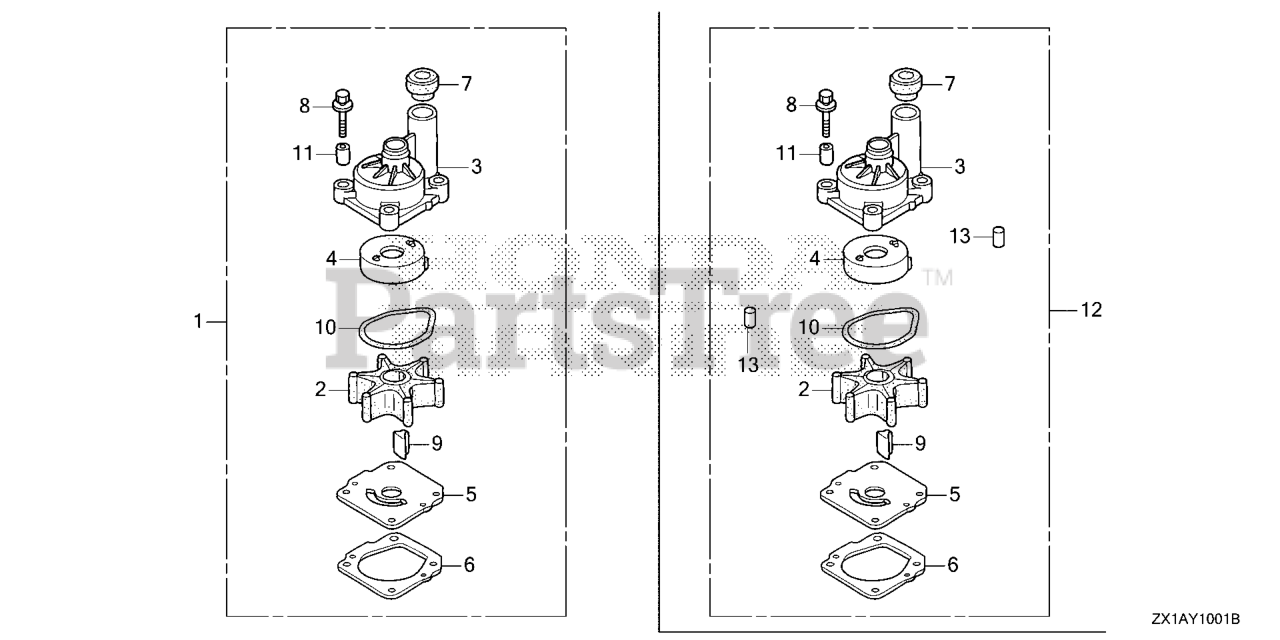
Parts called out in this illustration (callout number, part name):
1	PUMP KIT, IMPELLER
2	IMPELLER, PUMP
3	HOUSING, IMPELLER
4	LINER, PUMP
5	COVER, IMPELLER
6	GASKET B, IMPELLER
7	RING, WATER TUBE SEAL
8	BOLT-WASHER (8X40)
9	KEY, WOODRUFF
10	O-RING, WATER PUMP
11	COLLAR, DISTANCE
12	PUMP KIT, IMPELLER
13	PIN, DOWEL (6X10)
